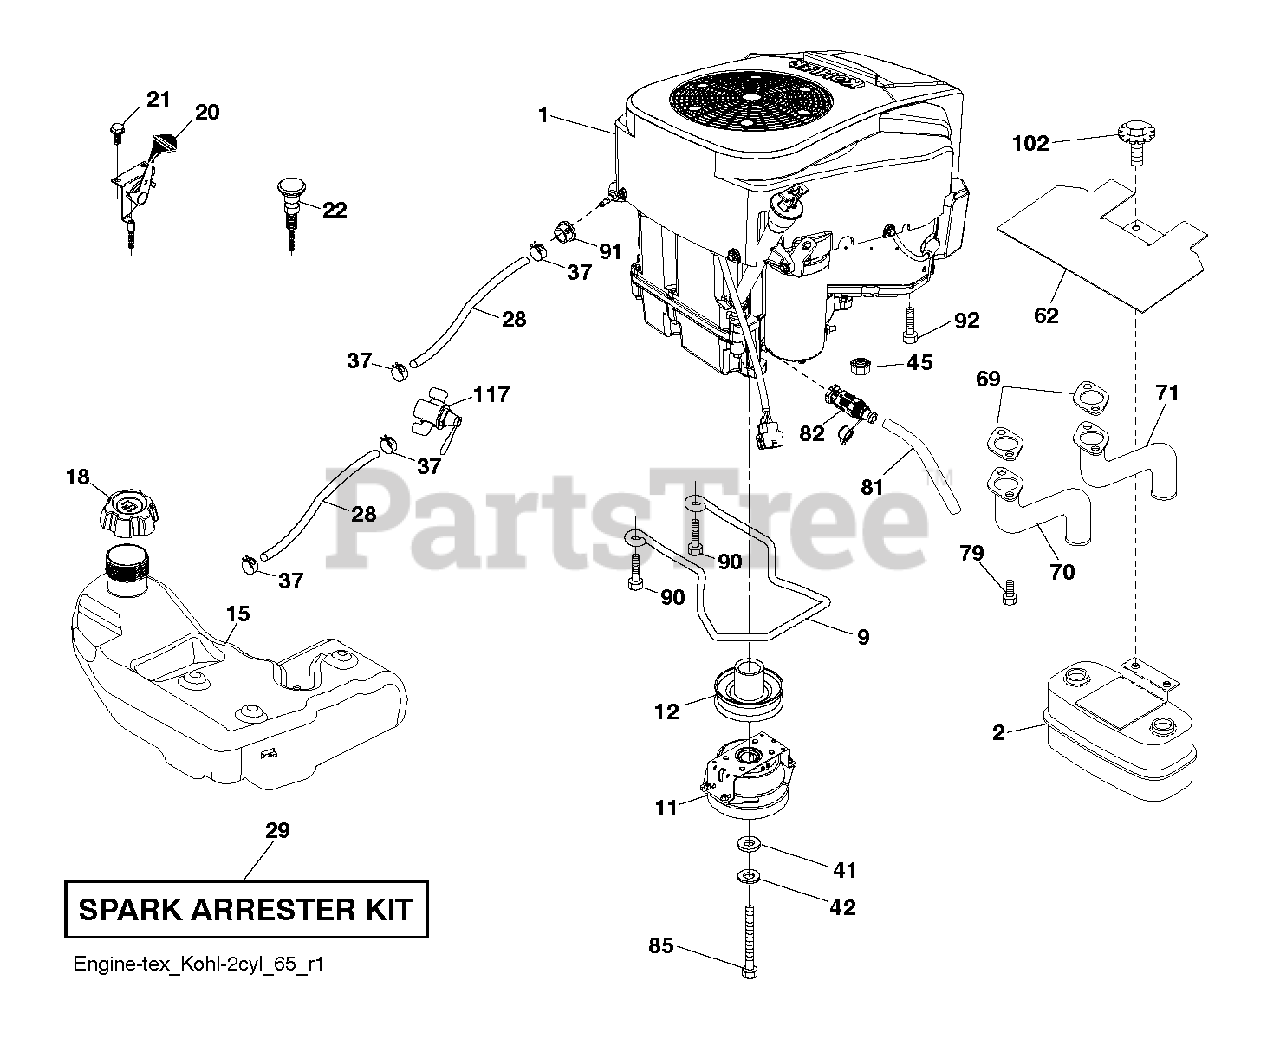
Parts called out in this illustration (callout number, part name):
2	Muffler Assembly, Twin MN
9	KEEPER.BELT.ENG.4.25"2.BLT.431
11	CLUTCH.OGURA.5.0PD.GT1.5A-EH01
12	PULLEY ENGINE
15	TANK.ASM.FUEL.4R.GAL.EPA.17
18	CAP ASSY FUEL 3" BLACK
20	THROTTLE CONTROL
21	SCREW.#10 X 0.750.BOS
22	CONTROL.CHOKE.ERGO.PUSH-IN.BLA
28	LINE.FUEL.64"REAR.EMIS
29	KIT.SPARK ARRESTOR 794945 B&S
37	HOSE CLAMP
42	WASHER 7/16 LOCK
45	NUT
62	SHIELD.HEAT.MUFFLER
69	GASKET.EXHAUST.KOHL.CV18-CV26
70	PIPE.EXHAUST.LH.CV18/20
71	PIPE.EXHAUST.RH.CV18/20
79	SCREW.SOCKET HD.5/16-1
81	TUBE, DRAIN OIL ASM.
82	VALUE.OIL.DRAIN
85	BOLT.HEX.7/16-20X3.GR5.YELLOW
90	SCREW 3/8-16X1
91	BUSHING.1.375OD
92	SCREW 3/8-16X1
102	SCREW
117	VALVE FUEL RESERVE
